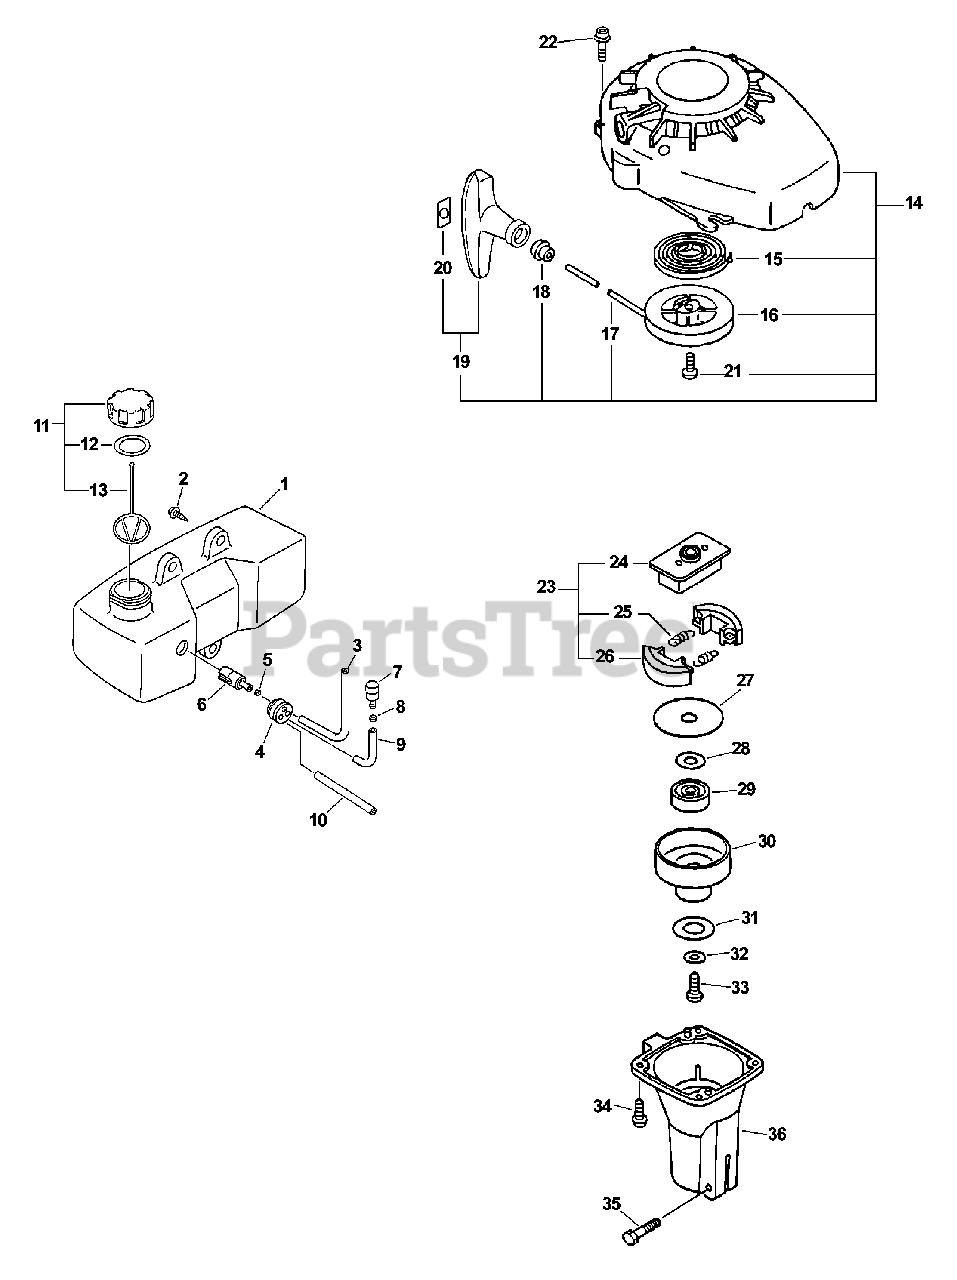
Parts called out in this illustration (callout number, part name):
1	TANK ASSY, FUEL
2	SCREW 5×15
3	PIPE, FUEL 3×5×210 BLACK
4	GROMMET, FUEL
5	CLIP 6 MM
6	FILTER, FUEL
7	VENT ASSY
9	PIPE, FUEL 3x-5x-70 BLACK
10	PIPE, FUEL 3×6×50
11	CAP ASSY
12	GASKET, FUEL CAP
13	CONNECTOR, CAP L= 100 MM
14	STARTER ASSY
15	SPRING, RECOIL
16	REEL, ROPE
17	ROPE, STARTER
18	GUIDE, ROPE
19	GRIP, STARTER
20	RETAINER, ROPE
21	SCREW
22	SCREW 4×16
23	CLUTCH ASSY
24	HUB, CLUTCH
25	SPRING, CLUTCH
26	SHOE, CLUTCH
27	PLATE, CLUTCH
28	WASHER 10.5×18×1.6
29	BEARING, BALL 6000-2RLB
30	DRUM, CLUTCH
32	WASHER, CLUTCH
33	SCREW 6×12
34	SCREW 4×14
35	BOLT 5
36	CASE, CLUTCH
